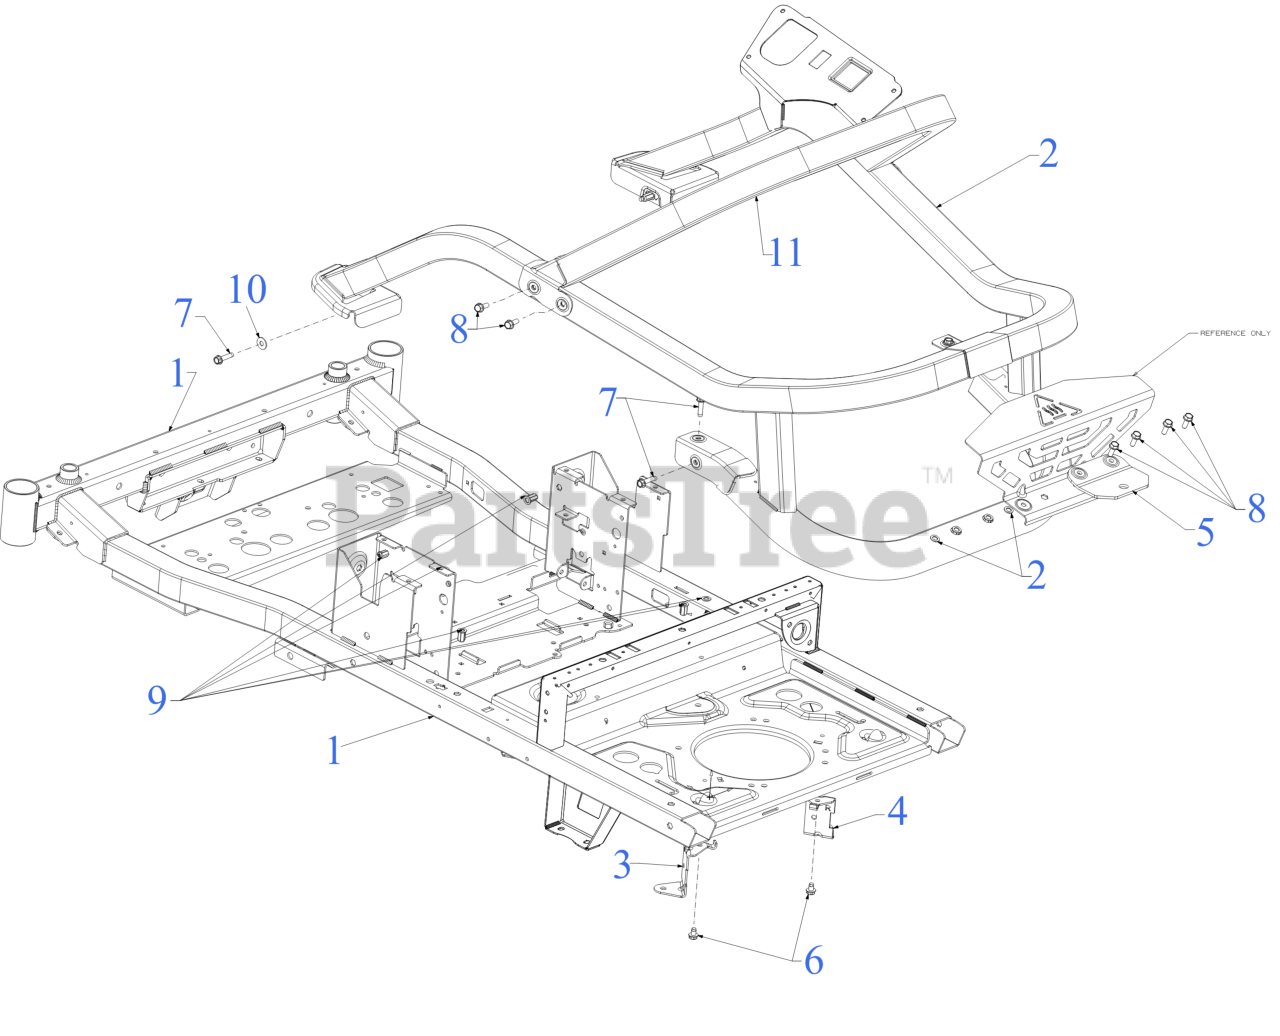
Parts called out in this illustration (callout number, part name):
1	FRAME
2	FRAME (UPPER)
3	TRANSMISSON MOUNT SUPPORT (LH)
4	TRANSMISSON MOUNT SUPPORT (RH)
5	HITCH PLATE
6	SCREW 5/16-18 x .500
7	SCREW 5/16-18 x 1.25
8	SCREW 5/16-18 x .875 GR5
9	NUT RIVET 5/16-18
10	FLAT WASHER
11	UPPER FRAME HOOP
